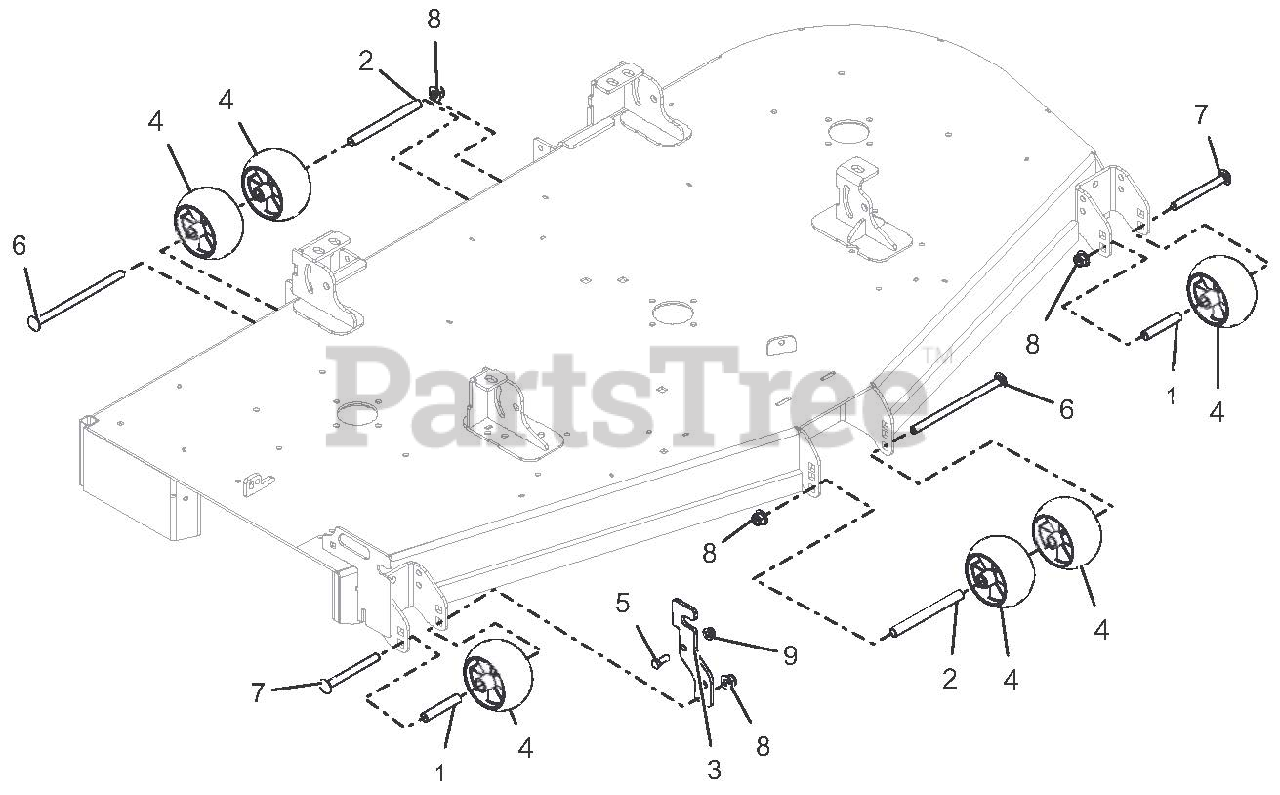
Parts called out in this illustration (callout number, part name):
1	SPACER, .510 X .625 X 3.35
2	SPACER, .510 X .625 X 6.50
3	CHUTE STORAGE BRACKET
4	ANTI-SCALP WHEEL - 5 X 3 CTR
5	BLT-HEX .38-16 X 1.00 GR5 YWZC
6	BLT-RDHDSQNK .50-13 X 8.50 Y
7	BLT-RDHDSQNK .50-13 X 5.00 GR5 YWZC
8	NUT-LK-NYL-FLG .50-13 YWZC
9	NUT-LK-NYL-FLG .38-16 YWZC
